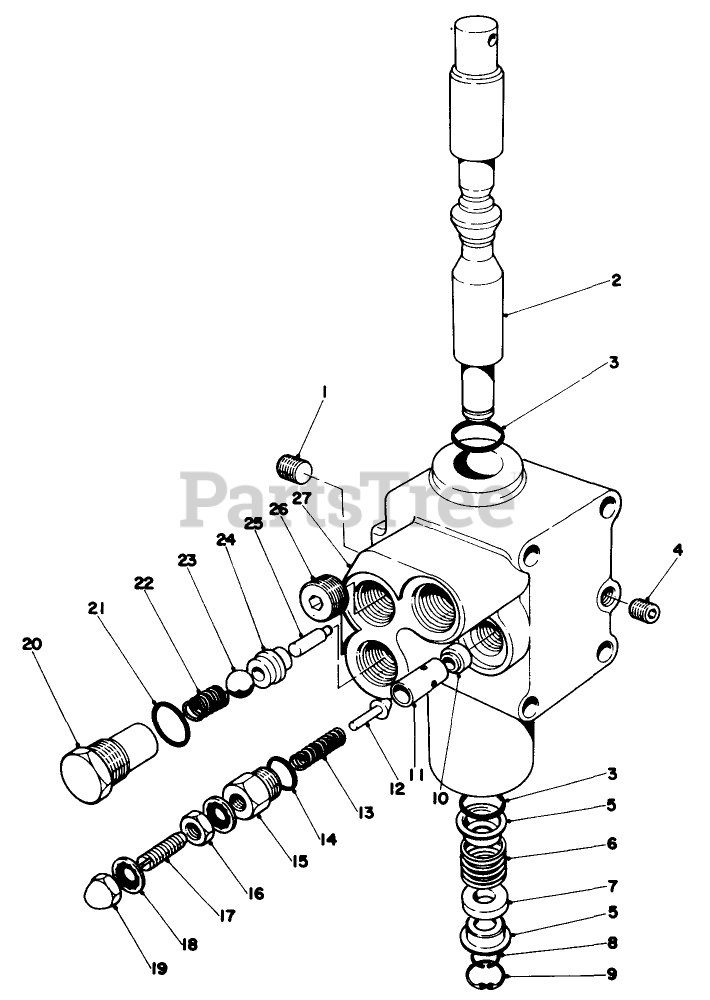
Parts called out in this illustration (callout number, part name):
2	SPOOL
3	O-RING
5	RETAINER
6	SPRING
7	FLOAT SPACER
8	RING-SNAP
9	RING-SNAP
10	VALVE SEAT (21-8550)
11	Guide
12	Plunger
15	Cap PV Adjustment
16	Jam Nut
17	Set Screw
18	Stat O-Seal
19	Acorn Nut
21	O-RING
22	SPRING
24	SEAT-VALVE
27	Body
